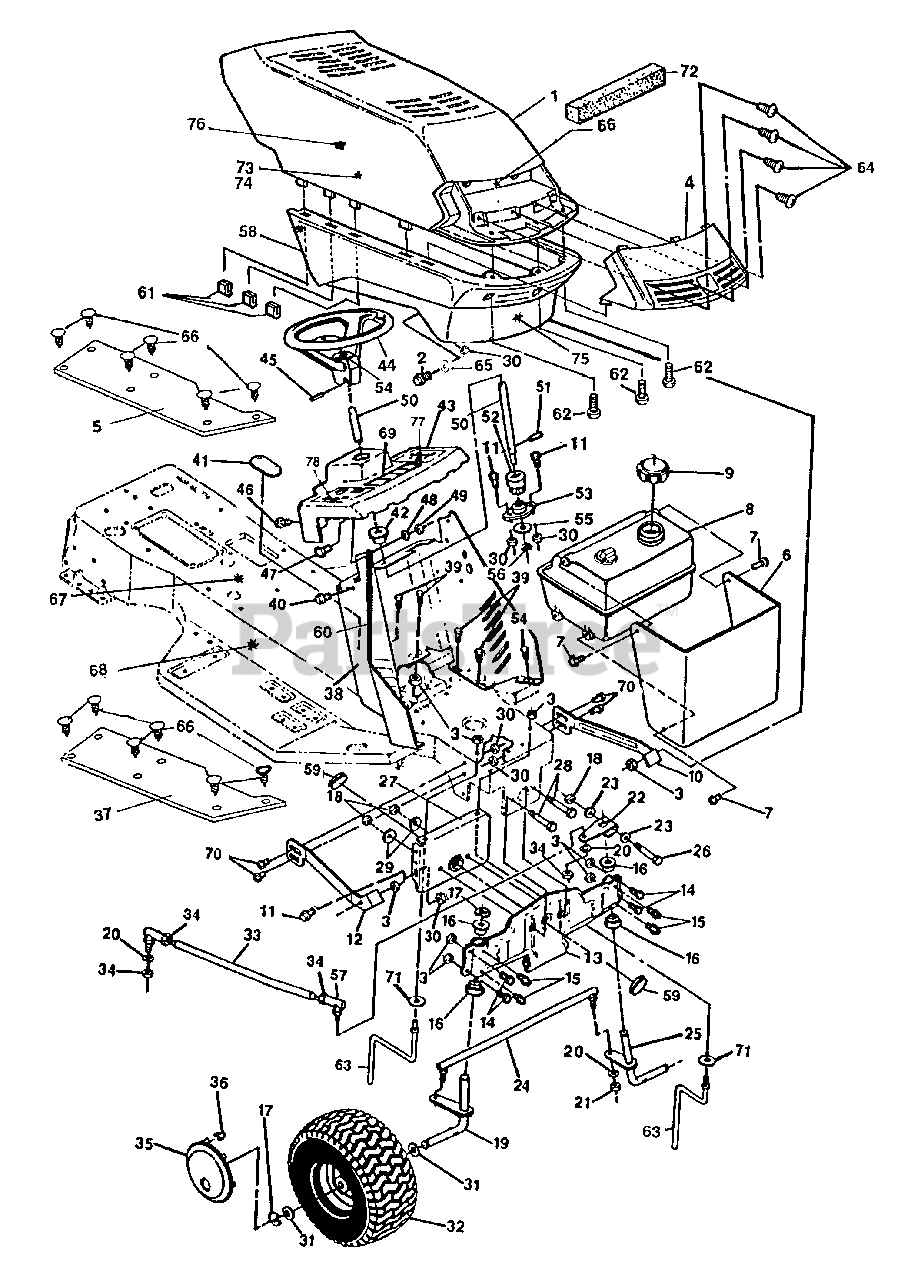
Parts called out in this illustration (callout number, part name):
2	Shoulder Bolt, 5/16-18 Thd.
3	Nut, Hx, Ctrlk, 5/16-18 Thd.
4	Lens, Headlight
5	Assembly, Foot Pad L. H.
6	Heat Shield, Gas Tank
7	Screw, Hx Hd, Plastite 1/4 Dia. x 3/4 In.
8	Tank, Gas 1.5 Gal W/Sensor
8	Low Fuel Sensor
9	Cap, Fuel
10	Bracket, Hood L. H.
11	Screw, Hx Hd, Wd Fl 5/16-18 x 3/4 In.
12	Bracket, Hood R. H.
13	Front Axle W/Bearings
14	Screw, Hx Hd, 5/16-18 x 5/8 In.
15	Grease Fitting
16	Bearing, Spindle
18	Nut, Hx, Ctrlk, 3/8-16 Thd.
19	Spindle, R. H.
20	Washer, Split, Lock 3/8 In.
21	Nut, Hx, 3/8-24 Thd.
22	Steering Arm, Upper
23	Washer, Flat, 25/64 In.
24	Assembly, Tie Rod
25	Spindle, L.H.
26	Screw, Hx Hd, 3/8-16 x 2-1/2 In.
27	Support Bracket, Front Axle
28	Screw, Hx Hd, 3/8-16 x 3 In.
29	Washer, Spring
30	Nut, Hx, Wd Fl Lk 5/16-18 Thd.
31	Washer, Flat, 3/4 In.
32	Wheel & Tire Assembly, Front
32	Tire, Rear
32	Valve Stem
33	Drag Link
34	Nut, Hx, Jam, 3/8-24 Thd.
35	Hubcap, Front
36	Clip, Hubcap
37	Assembly, Foot Pad R. H.
38	Dash, Lower
39	Screw, Tap, 5/16-18 x 3/8 In.
40	Screw, Self-Tap, 1/4-20 x 1/2 In.
42	Bushing, Upper Steering
43	Dash, Upper
44	Steering Wheel
45	Pin, , Spring,1/4 x 2 In.
46	Screw, Tap, 1/4-20 x 1/2 In.
47	Screw, Hx Hd, 1/4-20 x 5/8 In.
48	Washer, Flat, 9/32 In.
49	Nut, Hx, Ctrlk, 1/4-20 Thd.
50	Shaft, Steering
51	Pin, Dowel
52	Pinion, Steering
53	Bearing, Flange
54	Decal, Gunsight clear, Steering Wheel
55	Washer, Flat, 1/2 In.
57	Ball, Joint, 3/8 Thd.
59	Plug, Front Axle
60	Edging, Wide, 18 (dash)
61	Clip, Hood Trim
62	Screw, #10 x 1/2 In.
63	Belt Guide
64	Screw, #4-24 x 1 /2
65	Washer, Flat
66	Ratchet Fastener
67	Decal, Operating Instructions,
68	Decal, Wheel 4 Steer, LH & RH
69	Decal, Dash
70	Screw, Hex Wd Fl, 5/16-18 x 3/4 In.
71	Washer, Internal Tooth
72	Hood, Foam Baffle
73	Decal, Pin Stripe, RH
74	Decal, Pin Stripe, LH
75	Decal, Gunsight Clear Back
76	Decal, Hood
77	Decal, Dash L. H.
78	Decal, Dash R. H.
